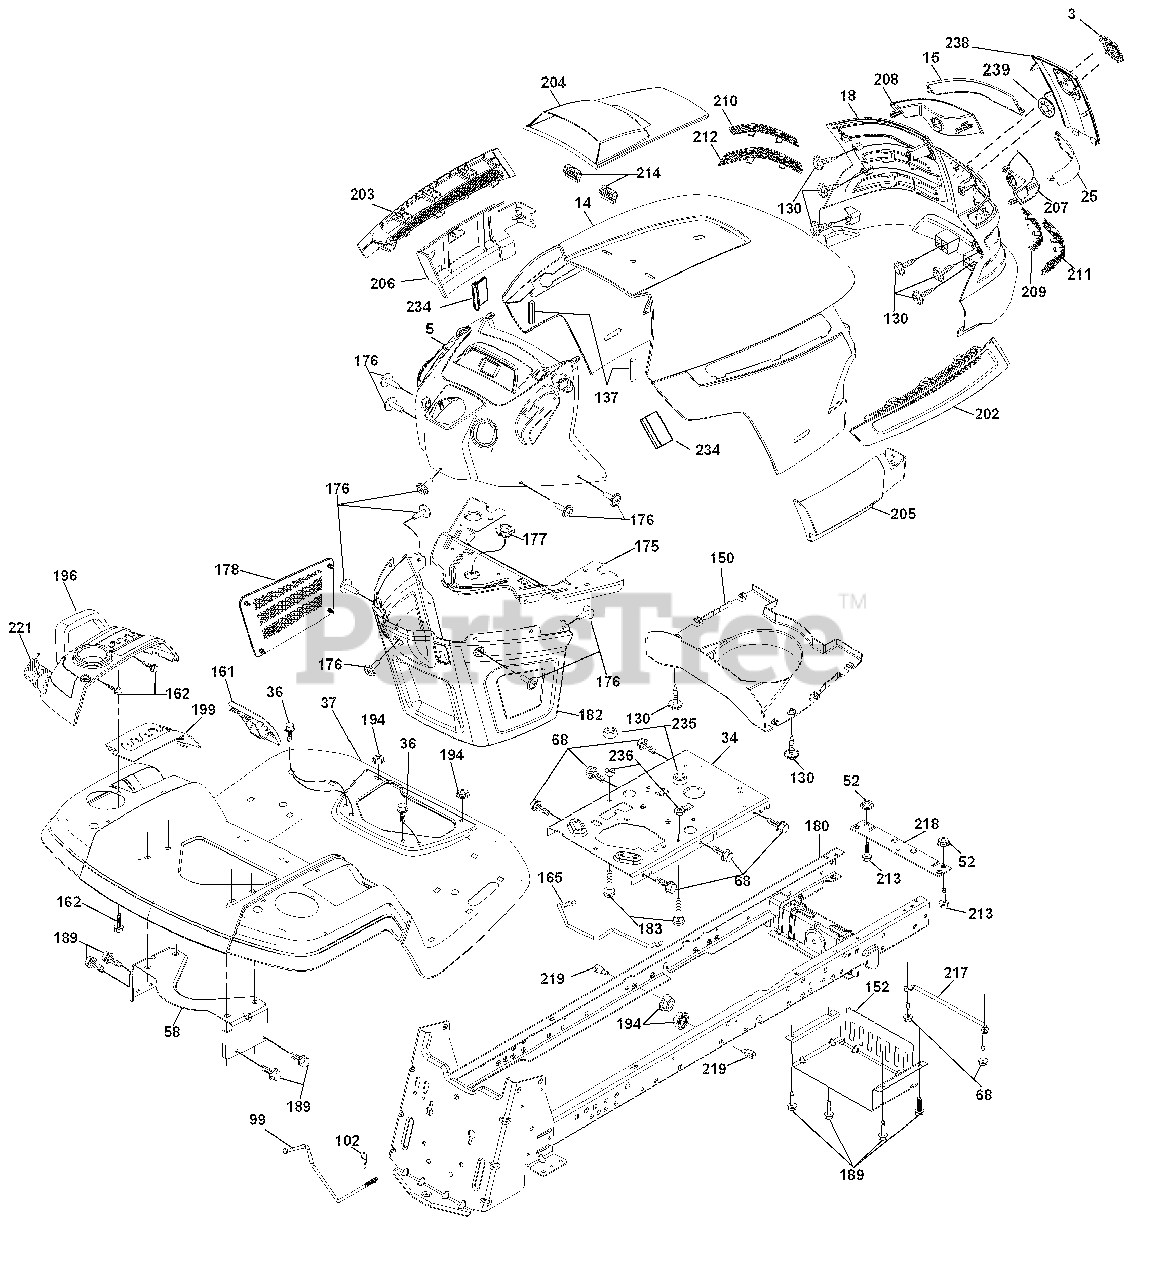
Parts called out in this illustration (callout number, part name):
3	Logo
14	Hood
34	Plate Engine
36	Screw 5/16 - 18 x 3/4
37	Fender
52	Nut Crown Lock 5/16-18
58	Bracket Fender
68	Screw 5/16-18 x 1/2
99	Rod Bypass Asm.
130	Screw 10 x 3/4 Single Lead Hex
137	Bumper Dash
150	Duct Heat Hood
152	Shield Browning/Debris
161	Console Fuel Window
162	Screw Hex Wsh Hi-Lo 1/4 x 1/2
165	Bracket Support Tank
175	Crossmember
176	Screw 10-24 x 5/8 Wshd Qdrx
177	Bushing Steering
178	Cargo Asm. Net
180	Chassis
182	Dash Lower
183	Bolt 5/16-18 UNC x 1-1/4
189	Screw 5/16-18 x 3/4
194	Nut Lock 5/16-18
196	Console Asm. Deck Lift
199	Plate Deck Lift
202	Vent Side Hood RH
203	Vent Side Hood LH
204	Vent Asm Hood Top
205	Skirt Hood Side RH
206	Skirt Hood Side LH
209	Insert Hex Top RH
210	Insert Hex Top LH
211	Insert Hex Bottom RH
212	Insert Hex Bottom LH
213	Bolt Hex Hd 5/16-18 unc x 3/4
214	Clip Retainer
217	Rod Pivot
219	Stud Fastener
221	Reflector LH
234	Bumper Hood
235	Spacer Fender
236	Nut Center Lock 5/16-18 UNC
